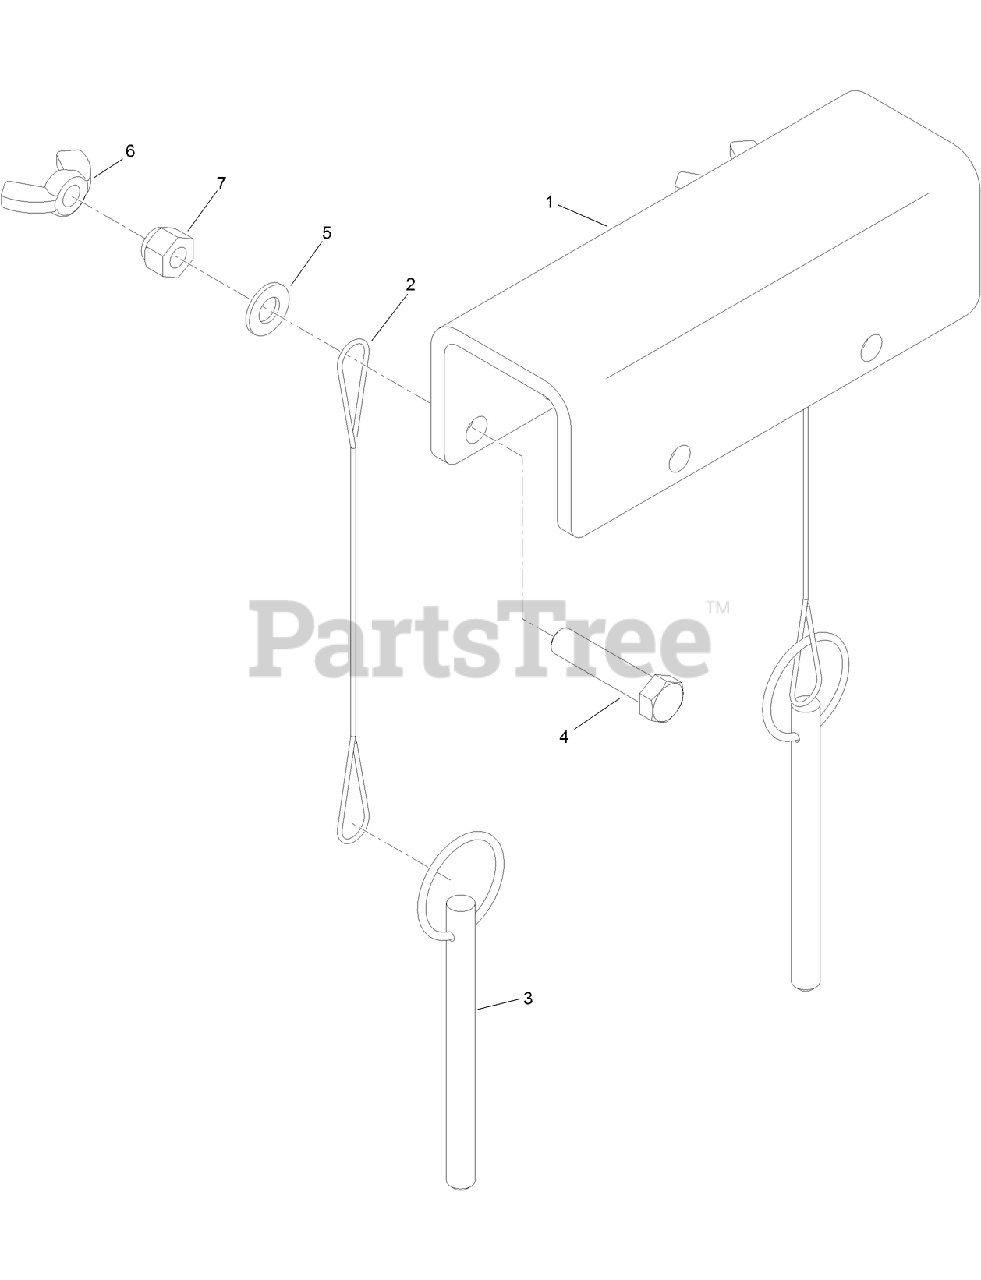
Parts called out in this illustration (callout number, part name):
1	LOCKOUT-CYLINDER, TILT
2	LANYARD-TETHER, PIN
3	PIN-RETAINING
4	SCREW-HH
5	WASHER-FLAT
6	NUT-WING
7	NUT-LOCK, NI
